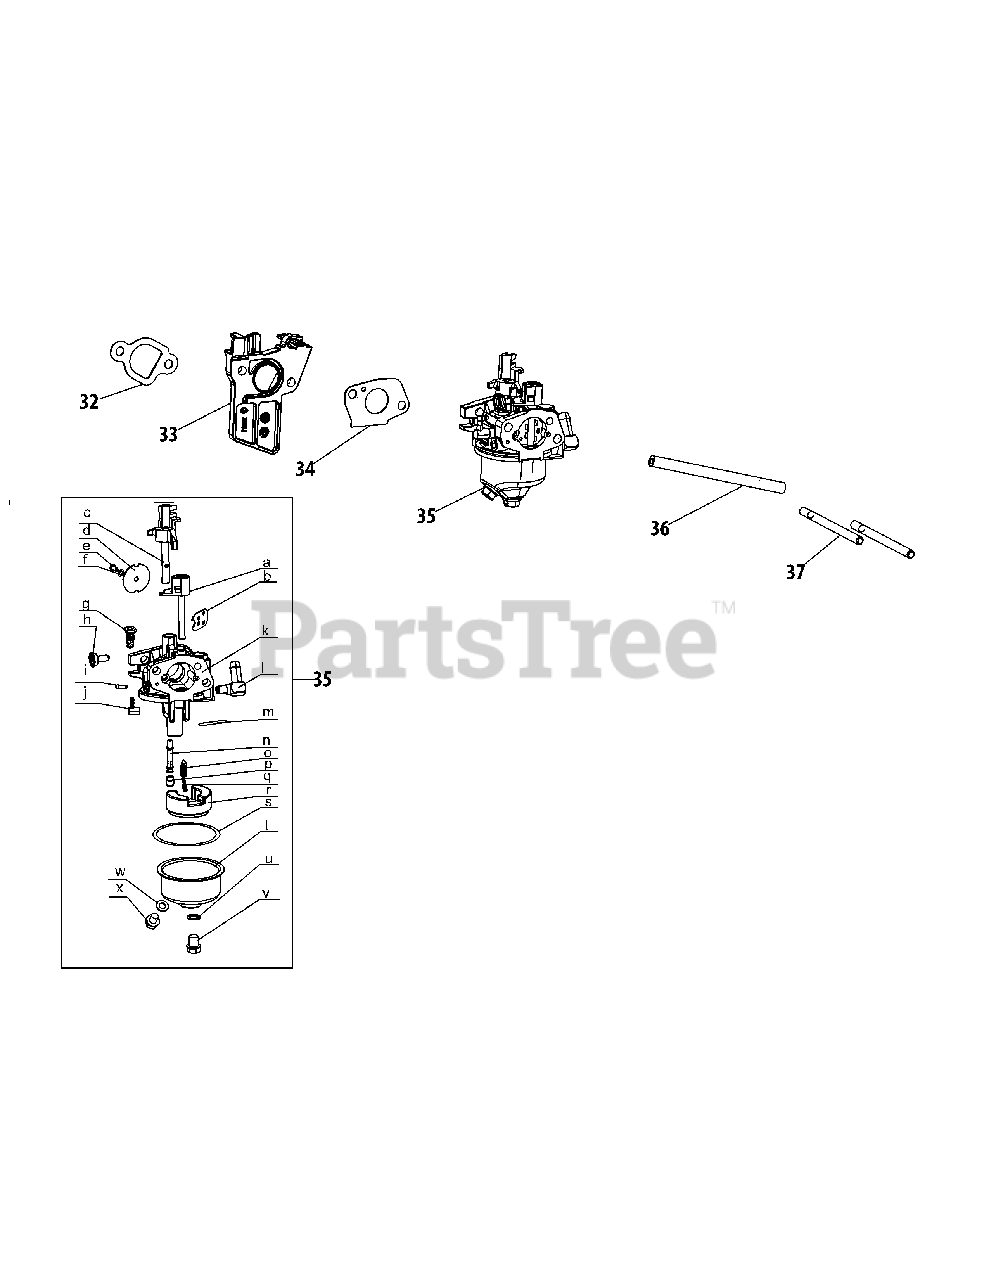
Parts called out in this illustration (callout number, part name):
32	Gasket, Carburetor Insulator
33	Insulator
34	Gasket, Carburetor
35	Carburetor
36	Fuel Hose,3.2×6.5×170
37	Stud, M6×92
